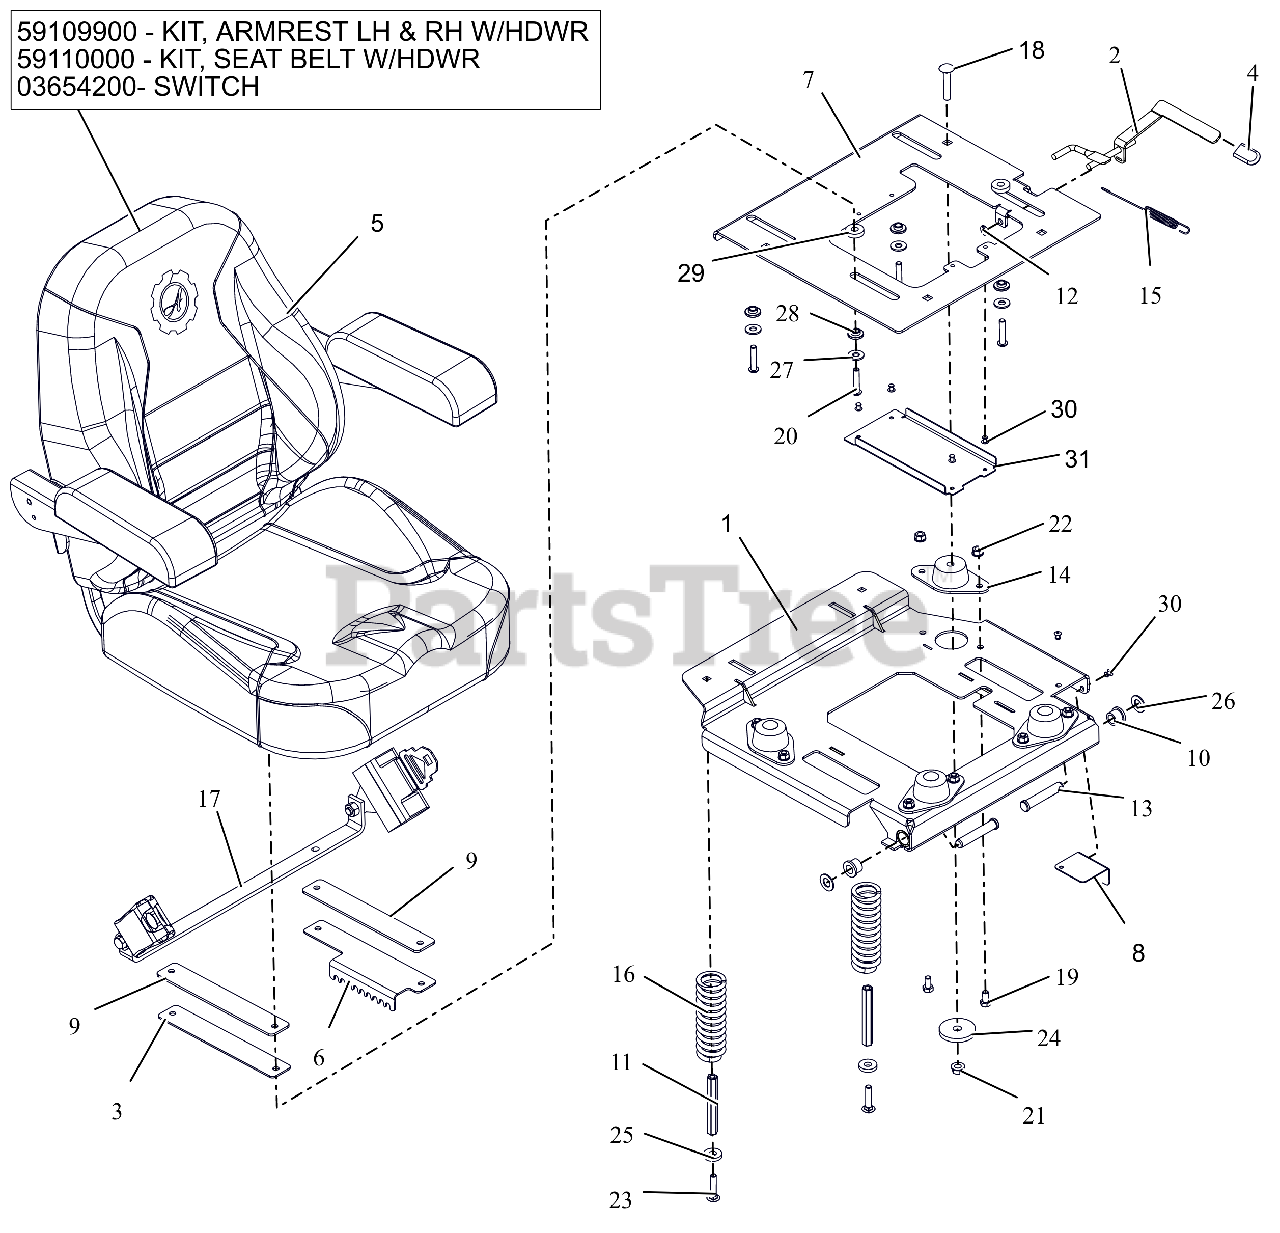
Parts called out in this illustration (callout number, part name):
1	WLDMT, ISO MTG PLATE (BLACK)
2	WLDMT, SEAT SLIDE LEVER
3	PLATE, ADJUSTABLE SEAT SLIDE
4	GRIP, SEAT LEVER, GREY
5	SEAT, APEX
5	KIT, LH&RH ARM REST-05007300
5	KIT-SEAT BELT REPLACE-05007300
5	SWITCH- SEAT
6	PLATE, HD SEAT ADJUSTMENT
7	PLATE, SEAT MOUNTING (ISO KIT) (ORANGE)
8	GUARD, SEAT FAN (SH)(BLACK)
9	SPACER, SEAT
10	BSHG, FLG .516X.750X.625X.937
11	NUT, COUPLING 5/16X18 X 3.75
12	NUT-PUSH .312
13	PIN-CLIC .50X2.70X2.31 -ZCC
14	MOUNT, FAIL-SAFE COMPRESSION
15	SG-TENS .06X.482X5.35
16	SPRING, COMPRESSION SEAT 224LB
17	KIT-SEAT BELT REPLACE-05007300
18	BLT,RHSSN.375-16X2.00 G5 ZCC
19	BLT, HEX .31-18X.625 G5 ZCC
20	BLT,SHCS-BTN .31-18X1.50 ZCC
21	NUT-LK-CTR-FLG .375-16 GF ZCC
22	NUT,LK-CTR-FLG .31-18 GF ZCC
23	BLT,RHSN .31-18X1.50 G5 ZCC
24	WSHR, FLT .469X2.00X.250 ZCC
25	WSHR, FLT .406X1.00X.188 ZCC
26	WSHR, FLT .531X1.00X.063 ZCC
27	WSHR,FLT .375X.875X.083 ZCC
28	BSHG-FLG .325X.499X.3X.875
29	WSHR, FLT .390X1.00X.250 ZCC
30	RIVET, .1875 AL/AL .126-.250
31	PLATE, SEAT GUARD (BLACK)
